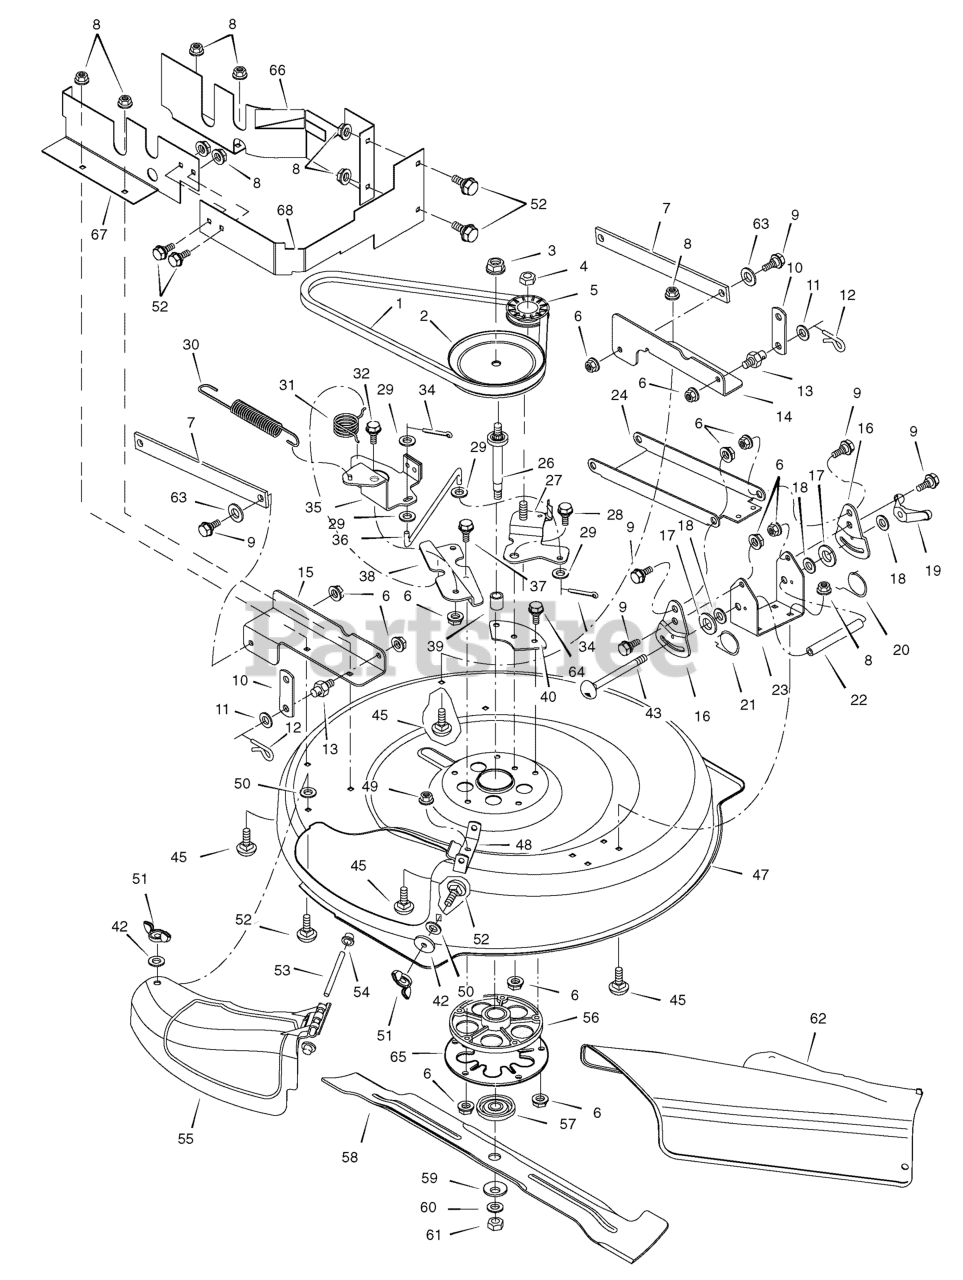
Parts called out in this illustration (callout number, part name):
1	BELT, Blade Drive
2	PULLEY, Input
3	LOCKNUT, 9/16-18
4	NUT, Flange, 3/8-16
5	PULLEY, Idler
6	NUT, Flange
8	NUT, Flange, 5/16-18
9	BOLT, Shoulder
12	PIN, Hair
13	PIN, Threaded Shoulder
14	BRACKET, Left Rear
15	BRACKET, Right Rear
16	PLATE, Adjustment
17	PAD, Friction
19	WINGNUT
20	SPRING, Left Torsion
21	SPRING, Right Torsion
22	TUBE, Spacer
23	BRACKET, Deck
24	HANGER, Front
26	SHAFT, Splined
27	ARM ASSEMBLY, Idler
28	BOLT, Shoulder, 3/8-16 x 5/8
29	WASHER
30	SPRING, Extension
31	SPRING, Torsion
32	BOLT, Shoulder, 3/8-16 x 5/8
34	PIN, Cotter
35	ARM ASSEMBLY, Brake
36	LINK, Idler Arm
37	BOLT, 3/8-16
38	BRACKET, Brake Mounting
39	SPACER, Jackshaft
40	PLATE, Idler Mounting
43	BOLT, Carriage
45	BOLT, Carriage, 5/16-18 x 5/8
47	HOUSING, Blade
48	HINGE, Mulching Cover
49	NUT, Flange, 5/16-18
50	NUT, Speed
51	WINGNUT
52	BOLT, Carriage, 5/16-18 x 3/4
53	ROD, Chute Deflector
54	CAP, Push
55	COVER, Mulch
56	MANDREL HOUSING
57	ADAPTER, Blade
59	WASHER, Cup
61	NUT, Blade Mount
62	DEFLECTOR, Chute
65	PLATE, Jackshaft Support
66	GUARD, Deck Left
67	GUARD, Deck Right
68	GUARD, Deck Front
